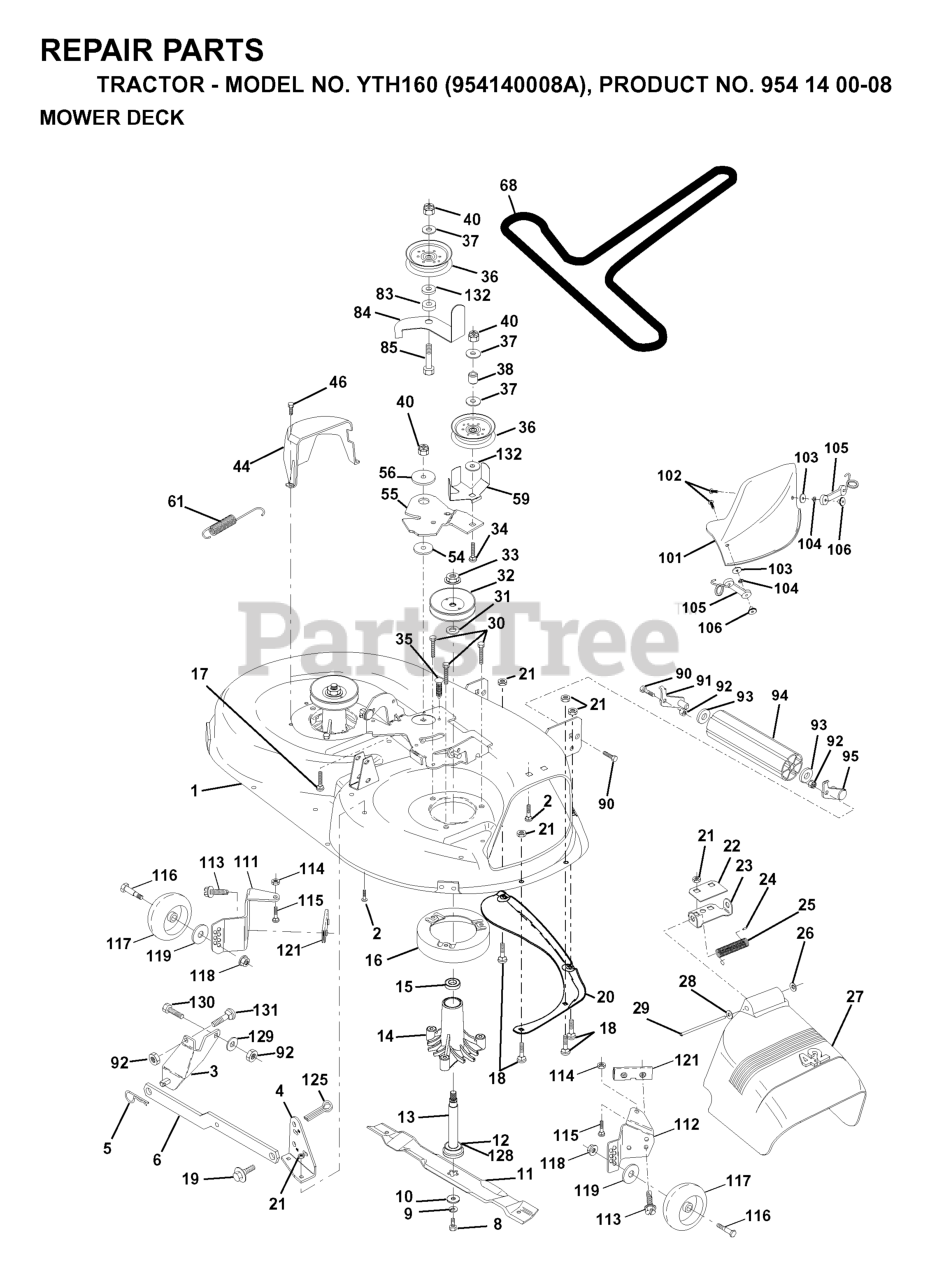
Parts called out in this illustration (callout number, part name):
1	LUG NUT 1/2F
2	WHEEL/TIRE.ASM.23X10.5-12.GREY
3	NUT 3/4-16 HEX SLTD GR5 ZD
4	CLEVIS PIN 3/8 X 1 1/8
5	HUB W/BRAKE DRUM
6	PIN COTTER 4MM X 45MM
7	MB WHEEL MOTOR
8	HCS 1/2C X 2 3/4
9	CLEVIS PIN
10	COMPRESSION SPRING
11	TRUNION PIN
12	BRAKE BAND
13	BRAKE BAND SUPPORT
15	MOTOR STANDOFF
16	BRAKE WLDMNT
17	ZERK
18	YOKE-3/8-24 PLTD
20	RP_COTTER PIN 1/8 X 3/4
21	BRAKE LEVER WLDMT
22	BRAKE CROSS SHAFT
23	LINKAGE - SHORT
24	GRIP, PARK BRAKE
25	WASHER, 7/16 DISC SPRING
26	YOKE-3/8-24 PLTD
29	FLANGE BEARING
30	NUT 3/8-16 NYLOC
31	HCS 3/8-16X1.GRD.5.ZD
32	RP_COTTER PIN 1/8 X 3/4
33	WASHER 3/8 FLAT
34	SLW 3/8 STD
35	HEX BOLT 3/8 X 1"
37	NUT HEX 1/2
38	WASHER 1/2" SPLIT LOCK
39	HCS 1/2C X 1 1/4 SERRATED HEAD
40	NUT 1/2-13 HEX NYLOC ZD
41	RETAINING RING, 7/8"
42	BSHG .875 X 1.375 X .074 ZD
44	NUT 3/8C WHIZ
45	NUT 3/8-16 NYLOC
46	HCS 3/8C X 2 1/2
47	HCS 1/4C X 3/4 HCS
48	NUT.1/4-20.HEX.NYLOC.ZD
539105983	RIM 0 OFFSET 8.5" WIDE
539107392	RIM.12X7.GRAY.+1".OFFSET.ZTR
539107431	TIRE.TURF.MASTER.23X10.5-12
539107432	TIRE - 23X8.5-12
539912234	VALVE STEM TR-412
